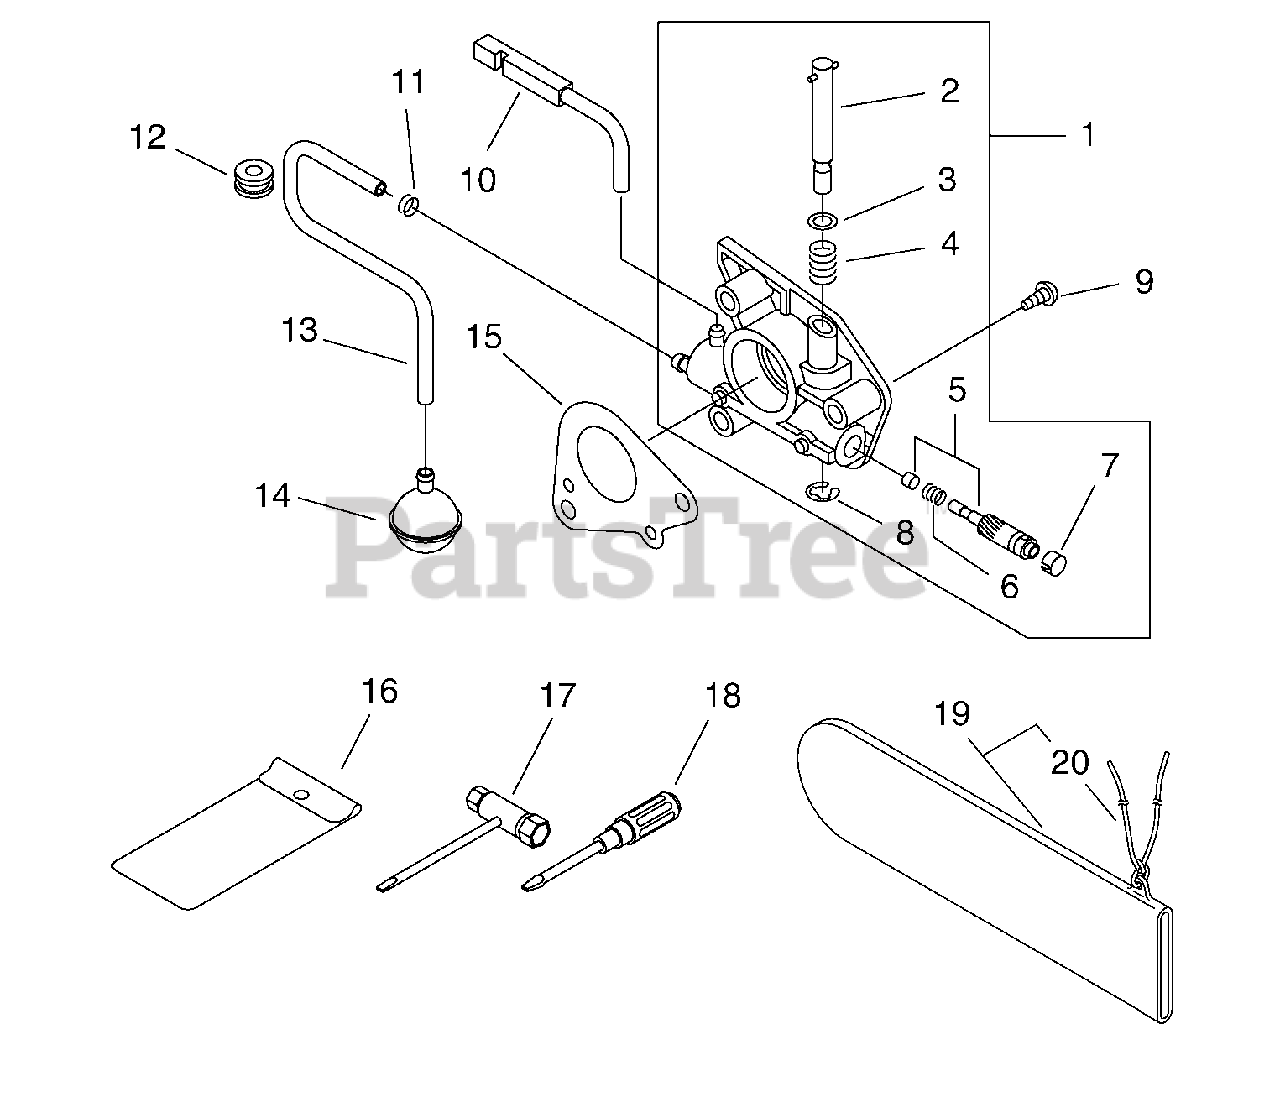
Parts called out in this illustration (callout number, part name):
1	AUTO-OILER ASSY
2	NEEDLE, ADJUST
7	CAP, OIL PUMP
8	RING, RETAINING
9	SCREW - 4X16
10	PIPE - OIL
11	CLIP - 6.5
13	PIPE - OIL
14	FILTER, OIL
15	SEAL, DUST
16	BAG, TOOL
17	T-WRENCH - 13X19mm
18	SCREWDRIVER
19	COVER, GUIDE BAR
